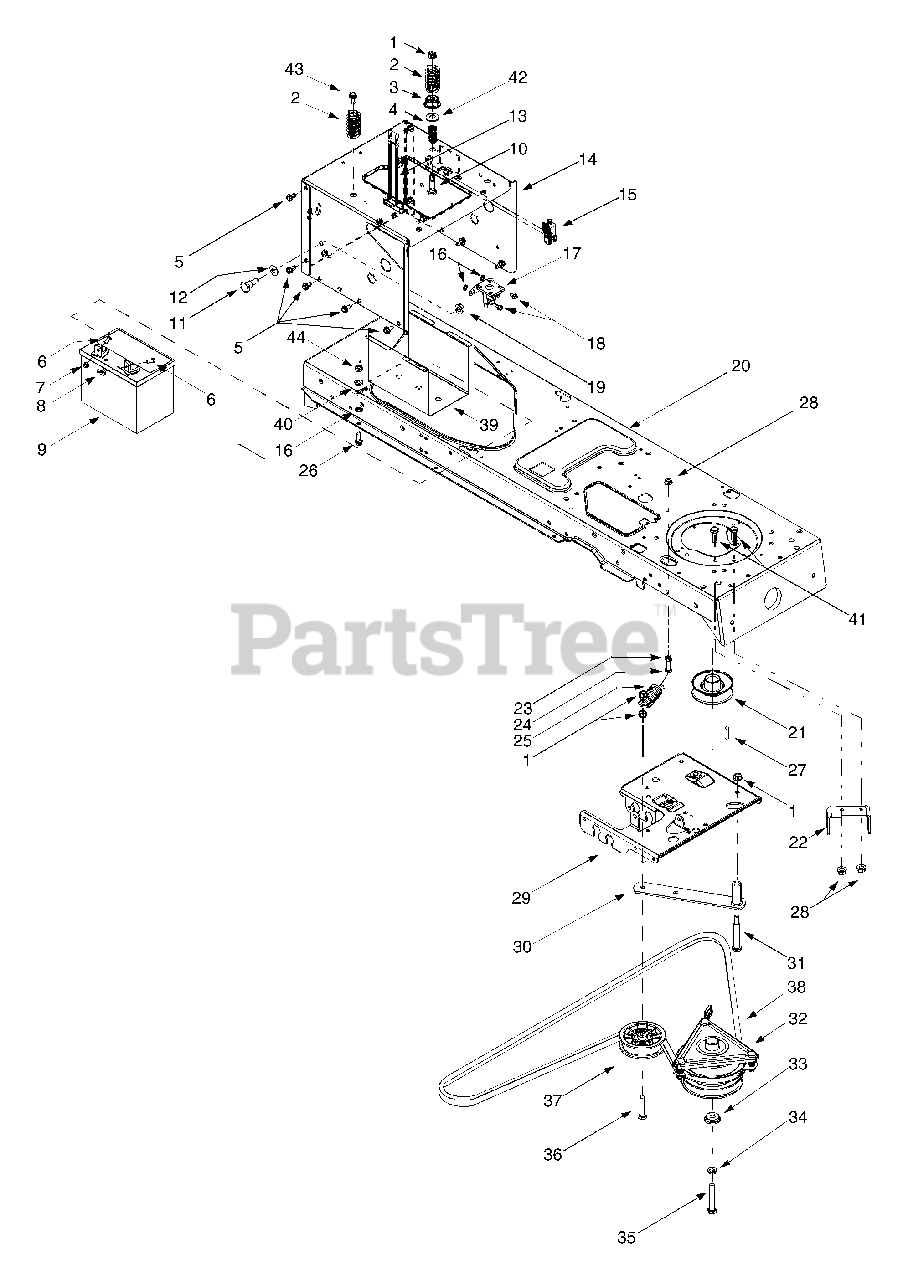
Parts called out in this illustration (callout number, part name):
1	Flange Lock Nut, 3/8-16
2	Compression Spring, 1.318 x 2.37
3	Spacer Cup, 1.5 OD
4	Compression Spring, .66 OD x 1.5
5	Self-tapping Screw, 5/16-18 x .625
6	Hex Cap Screw, 1/4-20 x .62
7	Hex Sems Nut, 1/4-20
8	Wing Nut, 1/4-20
9	12-volt Battery, 270 CCA
10	Shoulder Screw, .5 x 1.25, 3/8-16
11	Shoulder Screw, .625 x .5, 7/16-20
12	Bell Washer, .45 x 1.0 x .062
13	Battery Strap
16	Lock Washer, 1/4
17	Solenoid, 12-Volt, 100 Amp
18	Self-tapping Screw, 1/4-20 x .5
19	Flange Lock Nut, 7/16-20
24	Hex Cap Screw, 5/16-18 x 1.75
25	Extension Spring, 1.2 OD x 3.638
26	Self-tapping Screw, 1/4-20 x .750
28	Flange Lock Nut, 5/16-18
29	Steering Support Bracket
32	Electric PTO Clutch
33	Shoulder Spacer, 1.38 x .445 x .36
34	Lock Washer, 7/16
35	Hex Cap Screw, 7/16-20 x 3.25
36	Hex Cap Screw, 3/8-16 x 2.25
37	Flat Idler Pulley, 3.5 OD
38	PTO Belt
41	Hex Cap Screw, 5/16-18 x .625
42	Bell Washer, .401 x .870 x .063
43	Self-tapping Screw, 5/16-18 x .875
44	Hex Nut, 1/4-20
